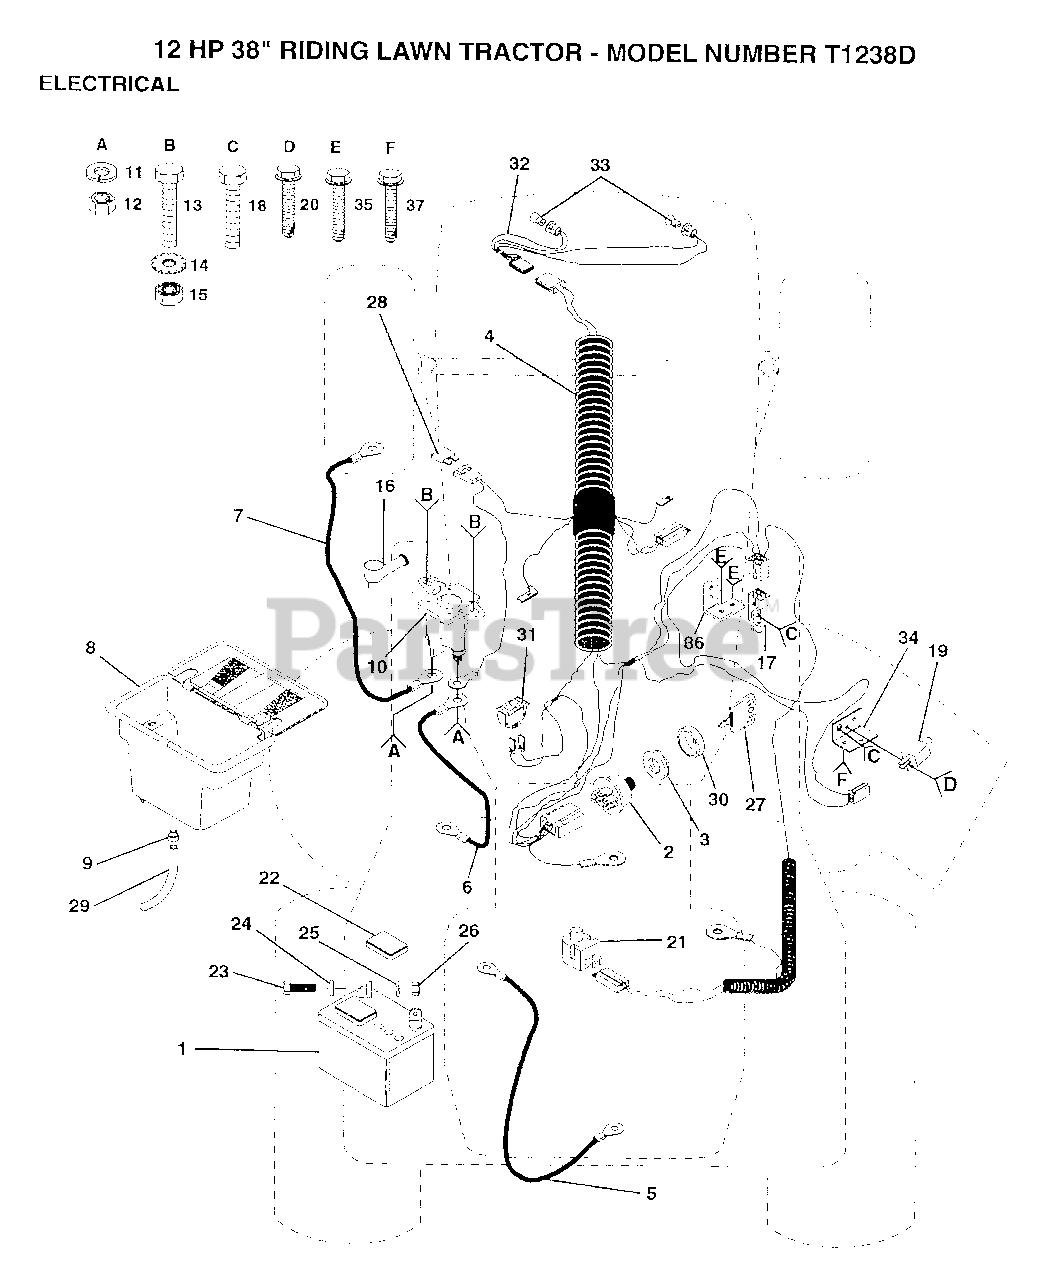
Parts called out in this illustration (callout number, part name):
3	NUT IGNITION
4	IGN HARNESS
5	CABLE T
7	"CABLE T, BATTERY"
9	HOSE CLAMP T
12	NUT
13	BOLT
15	NUT
17	SWITCH INTERLOCKT
18	SCREW
19	SWITCH-INTER. GT
20	SCREW
21	SWITCH SEAT
22	"CAP,BATTERY "
23	BOLT LT
24	WASHER
25	LOCKWASHER
27	KEY
28	FUSE HYT
31	SWITCH LT
34	SWITCH BRACKET
35	SCREW
36	BRACKET LT
37	SCREW
